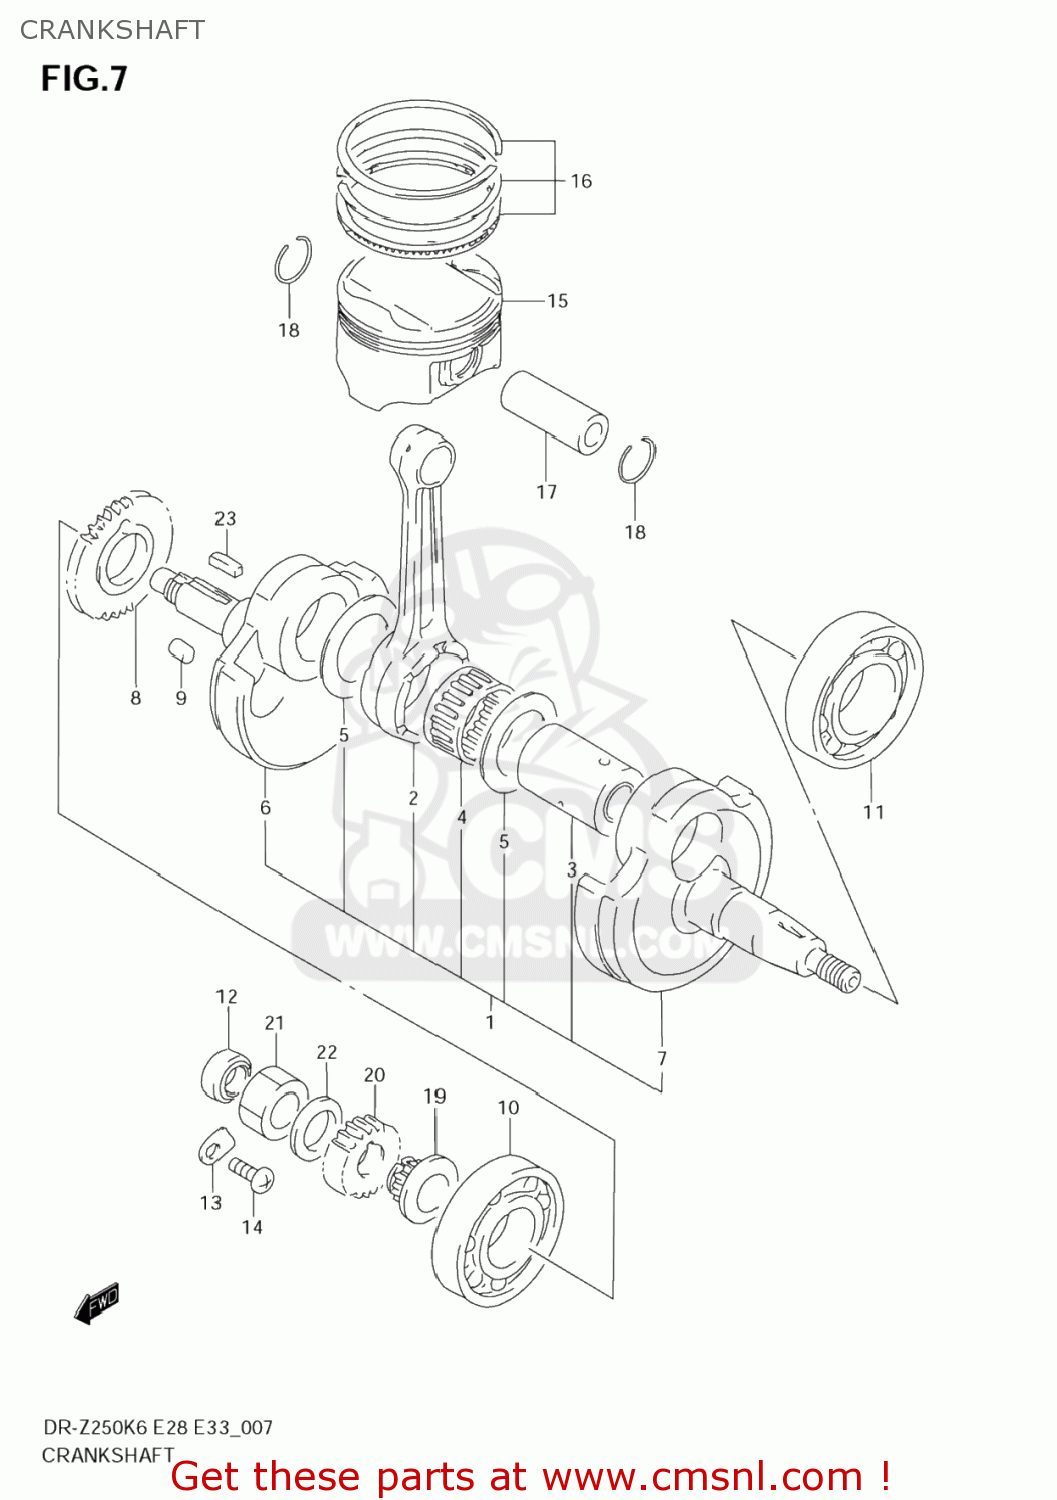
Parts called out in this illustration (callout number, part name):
1	CRANKSHAFT ASSY
2	CONNECTING ROD
3	PIN,CRANK
4	BEARING(34X43X20)
5	WASHER(34X52X1)
6	CRANKSHAFT,R
7	CRANKSHAFT,L
8	GEAR,CRANK BALANCER DRIVE
9	PIN(8X22.5)
10	BEARING(28X68X18)
11	BEARING(28X68X18)
12	SEAL,OIL(14X24X6)
13	RETAINER,BEARING
14	SCREW
15	PISTON
16	RING SET,PISTON
17	PIN,PISTON
18	RING,SNAP
19	SPROCKET,CAM CHAIN DRIVE
20	GEAR,PRIMARY DRIVE
21	NUT
22	WASHER
23	KEY
